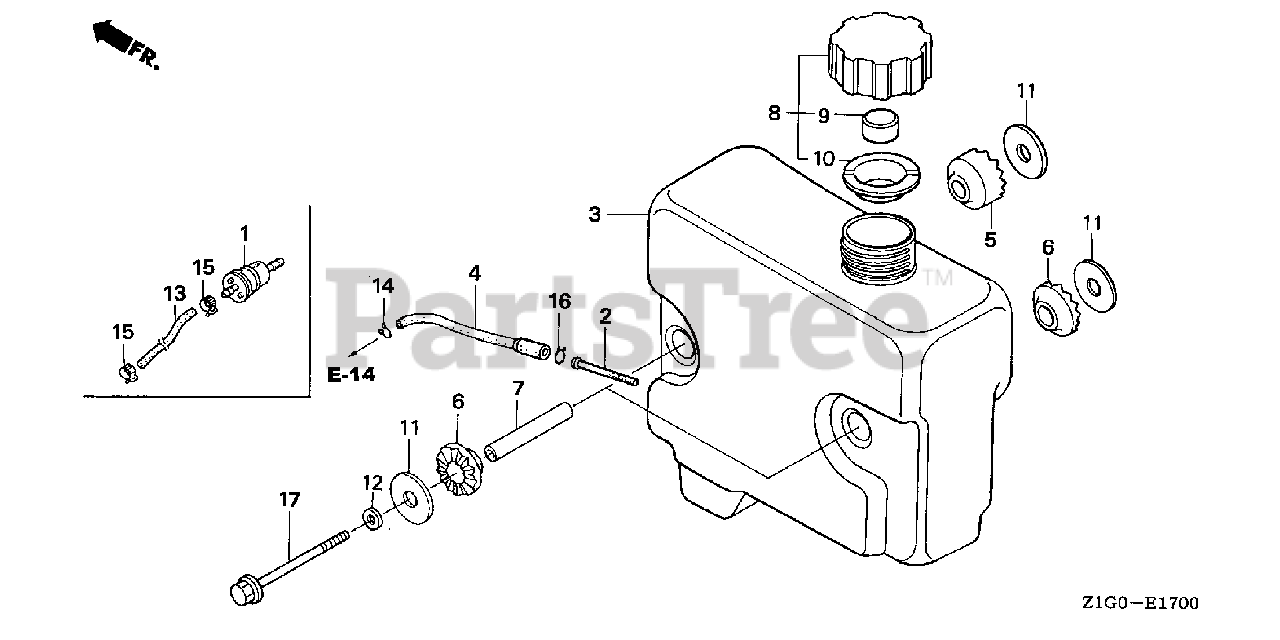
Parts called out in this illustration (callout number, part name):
1	STRAINER, FUEL
13	BULK HOSE, FUEL (4.5X3000) (4.5X230)
15	CLAMP, TUBE (D8.5)
